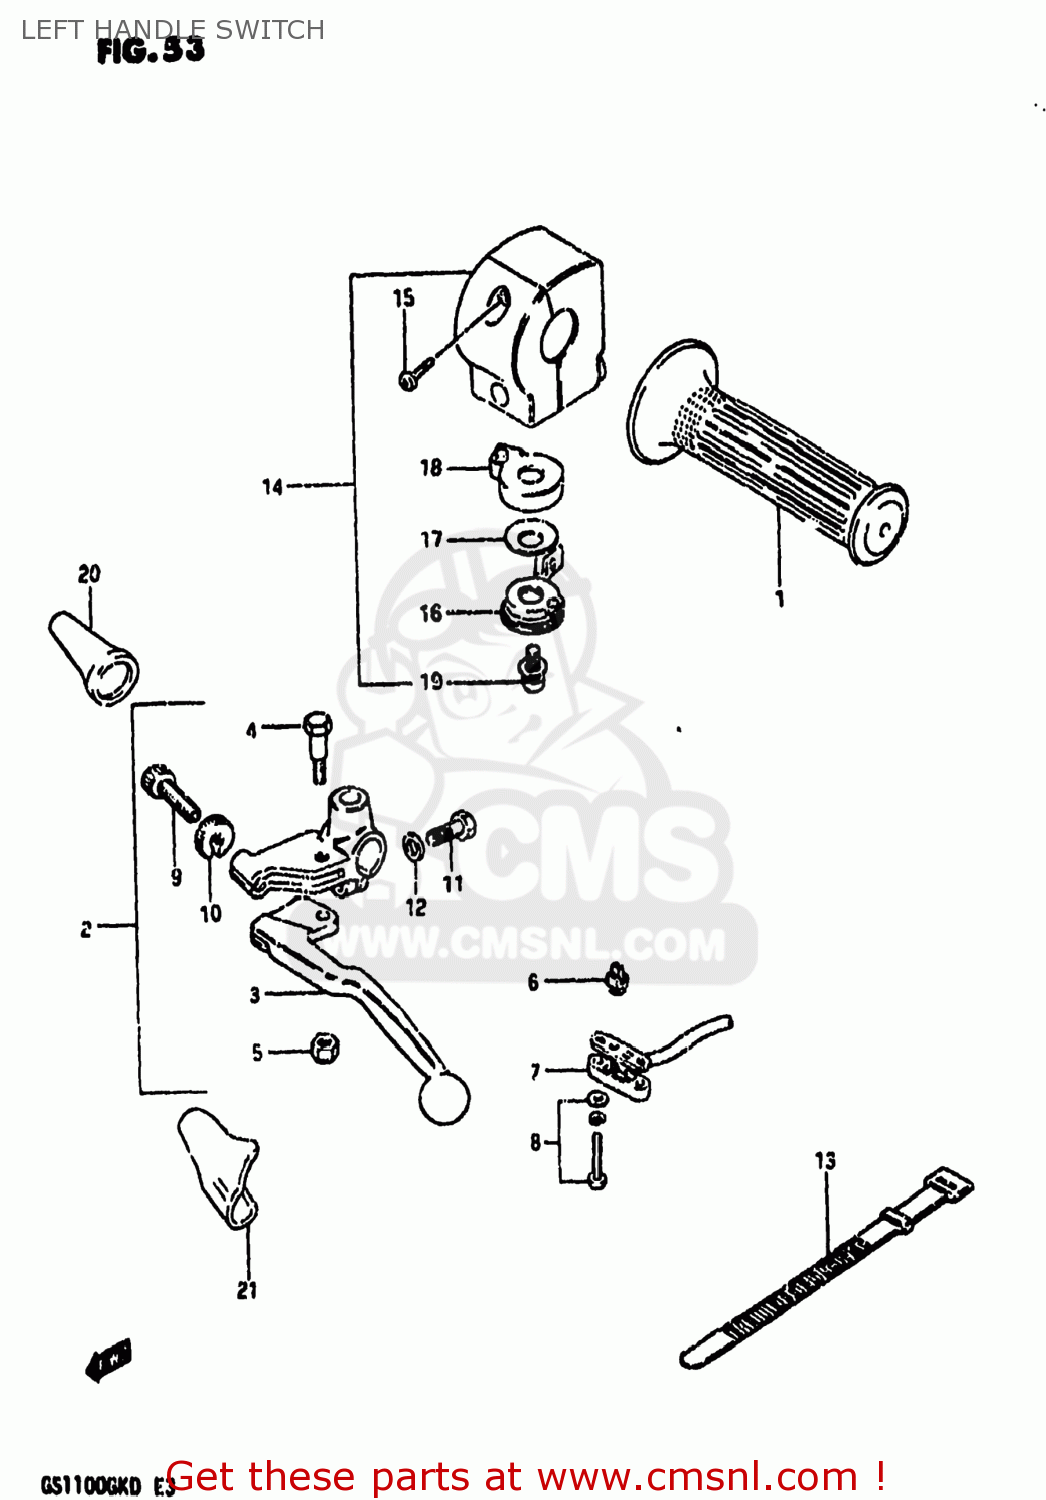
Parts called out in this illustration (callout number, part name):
1	GRIP,LEFT
2	LEVER ASSEMBLY
3	LEVER,CLUTCH
4	BOLT,LEVER
5	NUT 6MM
6	CONTACT,SWITCH
7	COVER,FR BK TERMINAL BASE
8	SCREW
9	NUT,CABLE ADJUSTER
10	NUT,CABLE ADJUSTER
11	BOLT,CLUTCH LEVER HOLDER
12	SPACER
13	CLAMP(L:120)
14	SWITCH ASSY,HANDLE,L
15	SCREW
16	LEVER,STARTER
17	WASHER,ADJUSTER
18	BODY,STARTER LEVER
19	SCREW,CHOKE LE
20	BOOT,CLUTCH CABLE
21	COVER,CLUTCH LEVER
